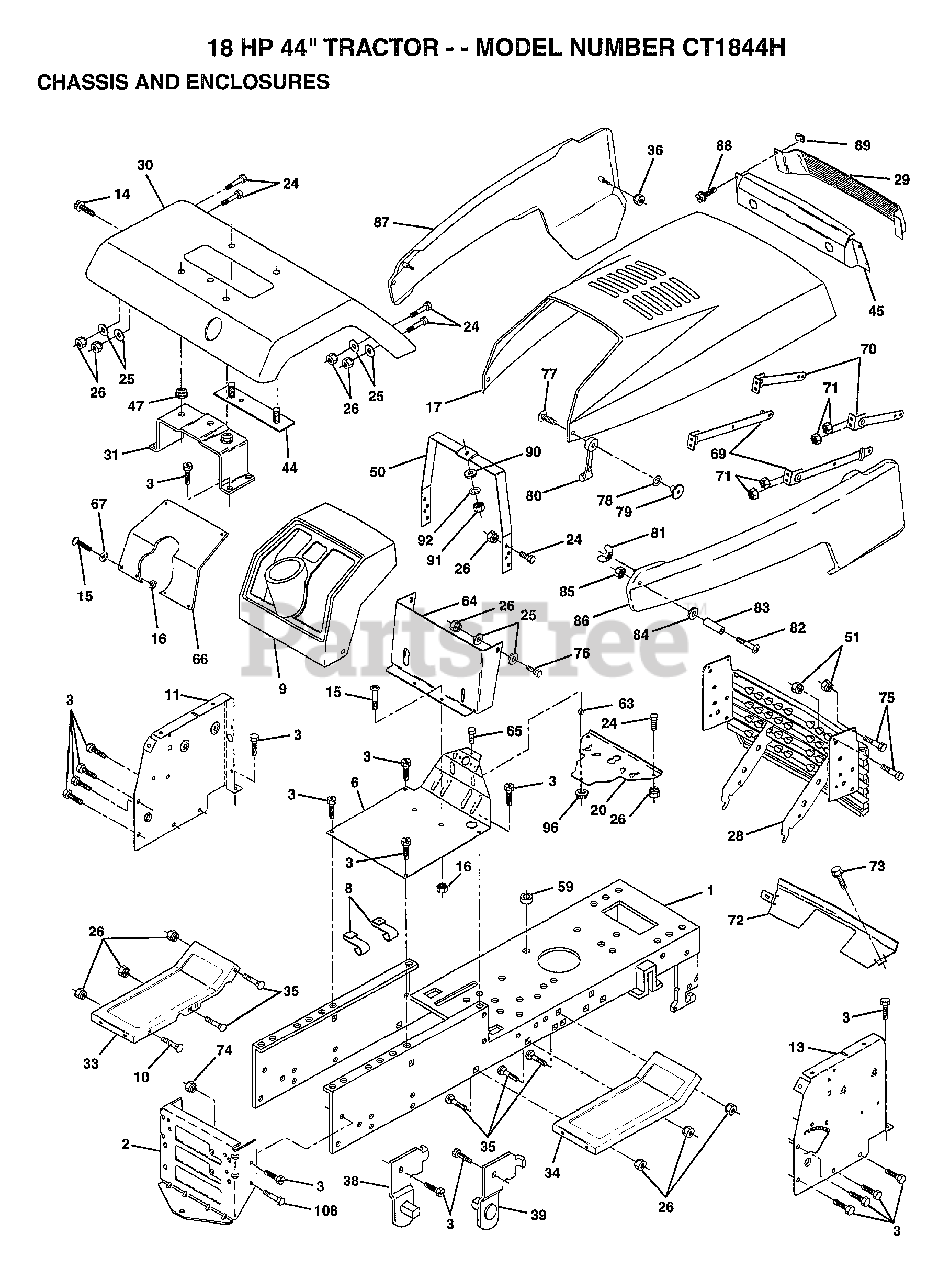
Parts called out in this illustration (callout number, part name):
2	DRAW BAR
3	SCREW
8	"CLIP,INSULATOR"
9	DASHBOARD BLACK
11	PANEL.DASH.LH
13	PANEL.DASH.RH
14	SCREW LT
15	SCREW
20	PLATE.SUPT.BATTER
24	BOLT
25	WASHER
29	LENS LT
30	FENDER PNT
31	BRKT.ASM.FENDER
35	BOLT
36	PAL NUT LT
38	BRACKET ASM LH
39	BRACKET ASM RH
44	STRAP ASM FENDER
47	NUT-PUSH YT
50	DASH.SUPT.YP/HUSQ
51	NUT
63	SPACER
64	LOWER DASH
65	BOLT
66	PLATE SLKSCR YP
67	WASHER
71	NUT
72	STRAP.PNT.GRILLE
73	SCREW CRT
76	BOLT
77	SCREW
78	LOCKWASHER
79	WELDNUT
80	HOOD LATCH T
82	SCREW
83	SPACER LT
84	WASHER
86	PANEL.SD.RH.YT/GT
87	PANEL.SD.LH.YT/GT
89	"""J"" FASTENER LT"
90	WASHER PM
92	LOCKWASHER
96	NUT
